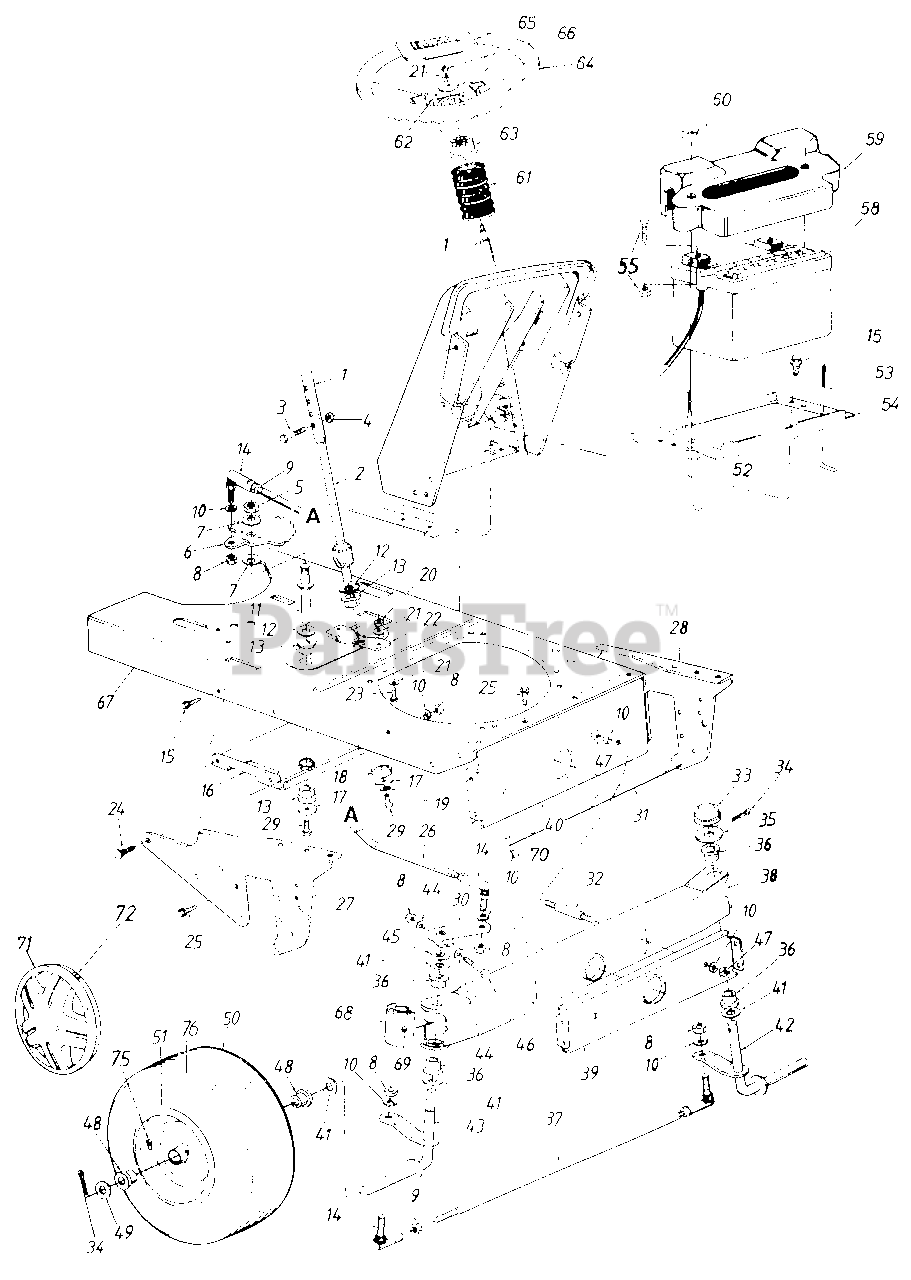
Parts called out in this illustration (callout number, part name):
1	Steering Column Ass'y.
2	Lower Steering Shaft
3	Hex Bolt 1/4-20 x 1.31" Lg.
4	Hex L-Nut 1/4-20 Thd.
5	Hex Nut 5/8-18 Thd.
6	Steering Gear Segment
7	Bell-Wash. 518" I.D. x 1.25n O.D.
8	Hex Nut 3/8-24 Thd.
9	Hex Jam Nut 3/8-24 Thd.
10	L-Wash. 3/8" I.D.
11	Steering Gear Segment Shaft
12	Fl-Wash. .64" I.D. x 1.24" O.D.
13	Hex Flange Brg. .63" I.D.
14	Ball Joint Ass'y.
15	Hex Wash. Hd. TT-Tap Scr. 1/4-20 x .5" Lg.
16	Deck Idler Support Brkt.
17	Fl-Wash. .33" I.D. x 1.25" O.D.
18	Spacer .985" I.D. x 1.25" O.D.
19	L-Wash. 5/16" I.D.
20	Hex Nut 5/16-24 Thd.
21	Bell-Wash. .345" I.D. x .88" O.D.
24	Ribbed Neck Bolt 3/8-24 x .8" Lg.
25	Hex Wash. TT-Tap Scr. 5/16-18 x .62" Lg.
26	Steering Drag Link
27	Pivot Bar Side Plate-R.H.
28	Pivot Bar Side Plate-L.H.
29	Hex Bolt 5/16-18 x .62" Lg.
30	Steering Arm
31	Deck Connecting Rod
32	Pivot Bar Shld. Bolt 3/8-16 x 518" Lg.
33	Cap
34	Cotter Pin 5/32" Dia.
36	Flange Brg. .757" I.D.
37	Tie Rod 20.25" Lg.
38	Pivot Bar Assy.
41	Fl-Wash. .76" I.D. x 1.49n O.D.
42	Front Axle Ass'y.-L.H.
43	Front Axle Ass'y.-R.H.
44	Bowed Washer
45	Spacer .755" I.D. x 1.25" O.D.
46	Hex Bolt 3/8-24 x 2.25n Lg.
47	Hex Nut 3/8-16 Thd.
48	Bronze Flange Brg.
49	Fl-Wash. .71" I.D. x 1.5" O.D.
50	Wheel Ass'y. Comp.
51	Rim Only
52	Push Nut
53	Battery Hold Down Rod
54	Battery Plate
55	Comes w/ Battery
58	Battery (275 Cold Crank Amps)
59	Battery Cover
60	Wing Nut Plastic 1/4-20 Thd.
61	Steering Bellow
62	Flat Washer
63	Steering Wheel Adapter
64	Steering Wheel
65	Steering Wheel Cap
66	Hex L-Nut 5/16-24 Thd.
67	Lower Frame
68	Pivot Bar End Cap
69	Grease Fitting
70	Internal Cotter Pin
71	Hub Cap
72	Spring Clip
75	Air Valve
76	Grease Fitting
